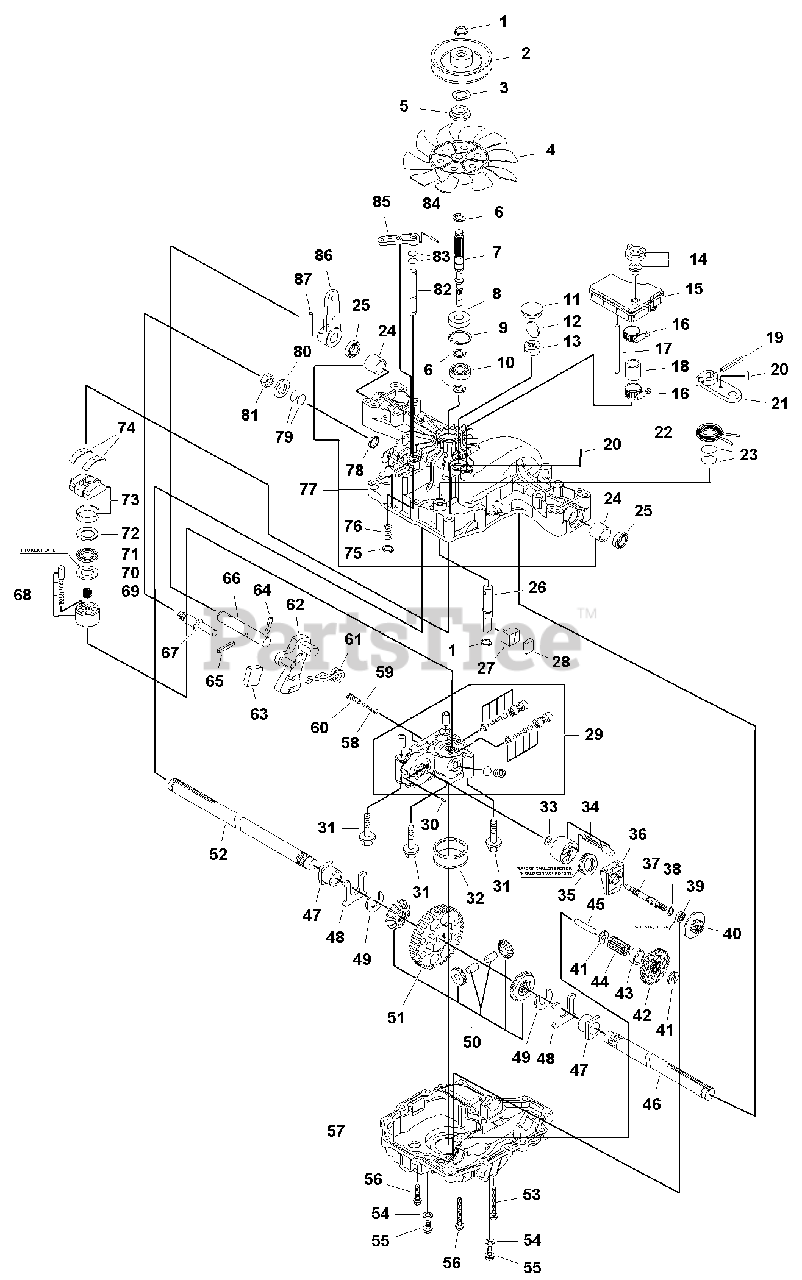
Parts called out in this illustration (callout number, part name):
1	SNAP RING
2	PULLEY
3	LOCK WASHER
4	FAN
5	SPLINE COLLAR
6	RING, "E"
7	PUMP SHAFT
8	SEAL
9	RING, Snap
10	BEARING
11	SEALING CAP
12	MAGNET
13	HOLDER, MAGNET
14	VENT VALVE
15	RESERVOIR TANK
16	MINIATURE CLAMP
17	SUPPORT
19	PIN
20	PIN
21	ARM, Brake
22	RETURN SPRING
23	O RING
24	BUSHING
25	SEAL
26	SHAFT, BRAKE
27	ACTUATOR, Brake
28	SHOE, BRAKE
29	CENTER CASE, Complete
31	BOLT
32	FILTER K55
33	WASHER
34	CYLINDER BLOCK
35	BEARING
36	HOUSING
37	SHAFT MOTOR
38	RING, Snap
39	BEARING
40	MOTOR GEAR
41	WASHER
42	REDUCTION GEAR
43	COLLAR, Final
44	FINAL PINION
45	REDUCTION SHAFT
46	AXLE SHAFT, LH
47	BUSHING
48	THRUST WASHER
49	RING
50	DIFF PINION, Kit
51	FINAL GEAR
52	AXLE SHAFT, RH
53	SCREW, Tapping
54	WASHER, Seal
55	SCREW, Cap
56	TAPPING SCREW
57	LOWER HOUSING
58	IDS SPRING
59	BALL, 3/16
60	IDS VALVE
61	SPRING, Torsion
62	CONTROL ARM
63	JERKY PLATE
64	COTTER PIN
65	PIN, SPRING
66	CONTROL SHAFT
67	FULCRUM, Eccentric
68	CYLINDER BLOCK
69	SPRING, Pump
70	THRUST PLATE
71	BEARING
72	THRUST PLATE
73	SWASH PLATE COMPLETE
74	THRUST METAL
76	SPRING
77	UPPER HOUSING
78	OIL SEAL
79	O RING
80	WASHER
81	NUT
82	SHAFT, Bypass
83	O RING
84	ROLL PIN
85	LEVER, Bypass
86	CONTROL LEVER
87	PIN, Roll
